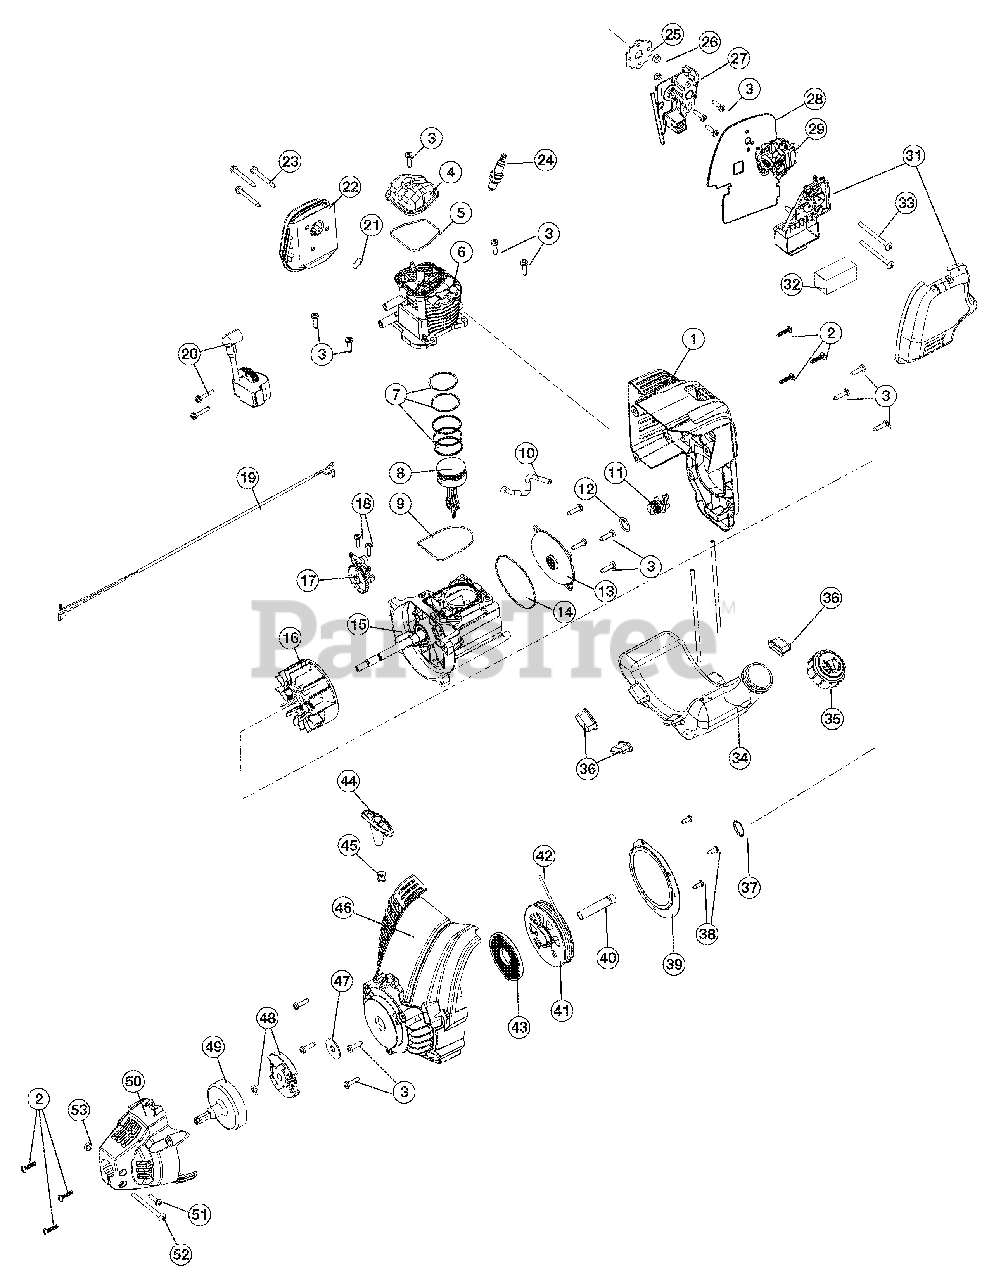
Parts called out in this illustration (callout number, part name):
1	Engine Cover Assembly
2	Cover Screw
3	Screw
4	Rocker Cover
5	Rocker Cover O-Ring
6	Cylinder Assembly
7	Piston Ring Assembly
8	Piston Assembly
9	Cylinder O-Ring
10	Breather Hose
11	Oil Plug
12	Oil Plug O-Ring
13	Crank Case Cover
14	Crank Case Cover O-Ring
15	Crank Case Assembly
16	Flywheel Assembly
17	Cam Bracket Assembly
18	Cam Bracket Screw
19	Lead Wires
20	Module Assembly
21	Muffler Gasket
22	Muffler Assembly
23	Muffler Screw
24	Spark Plug
25	Insulator Gasket
28	Carburetor Gasket
29	Carburetor w/Primer
31	Air Cleaner Cover Assembly
32	Air Filter
33	Screw
34	Fuel Tank Assembly w/ Fuel Lines
36	Fuel Tank Pads
38	Pressure Plate Screw
39	Pressure Plate
41	Starter Assembly
43	Recoil Spring
44	Handle
46	Starter Housing Assembly
48	Clutch & Clutch Washer
49	Clutch Drum
50	Clutch Cover
51	Anti-Rotation Screw
52	Clamp Screw
53	Nut
